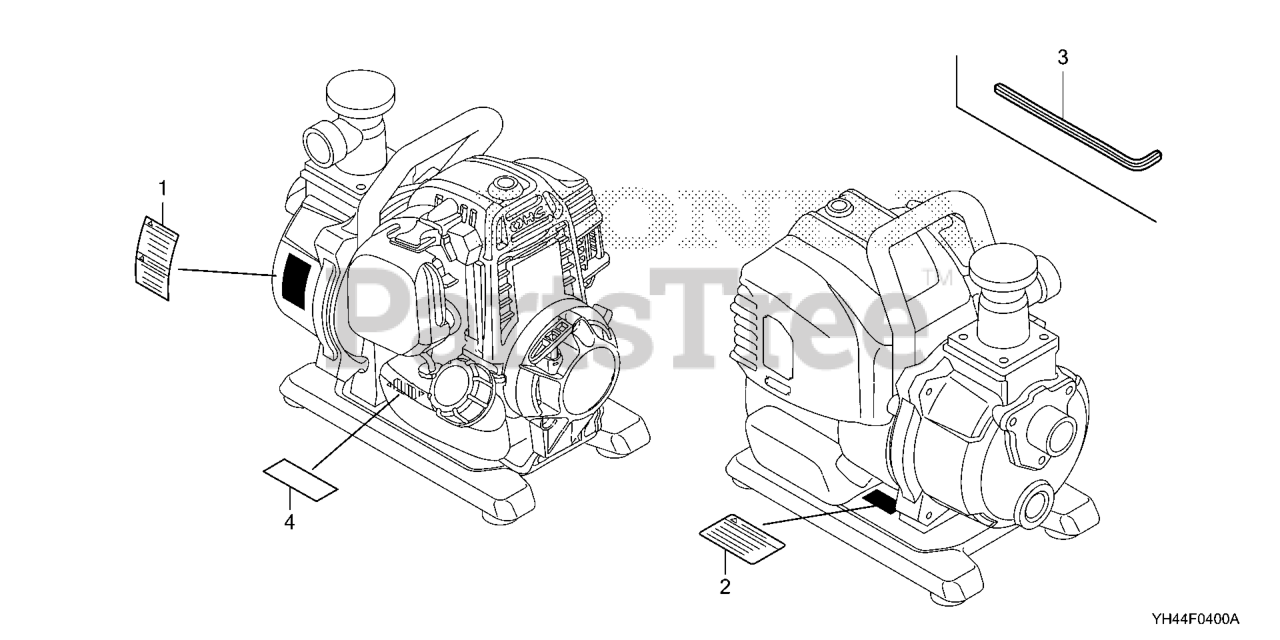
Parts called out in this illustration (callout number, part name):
1	MARK, CAUTION (PUMP)
2	LABEL, PUMP WARNING
3	WRENCH, HEX. (4MM)
4	LABEL, WARNING
